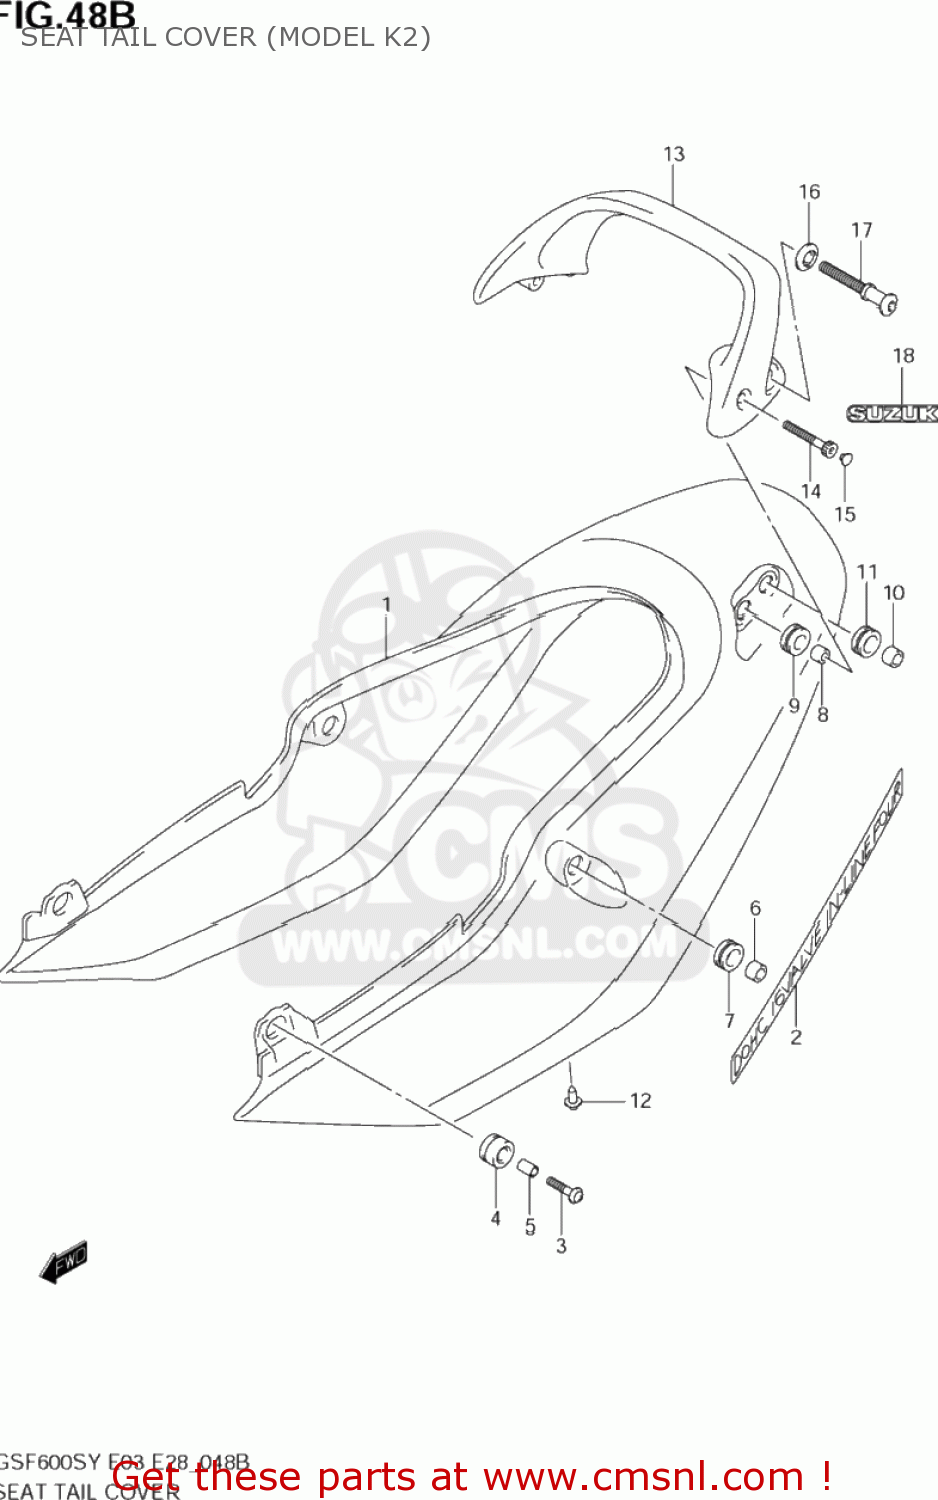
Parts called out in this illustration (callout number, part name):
1	COVER,SEAT TAI
2	EMBLEM,SEAT TAIL COVER(SILVER)
3	SCREW(6X30)
4	CUSHION,SEAT TAIL COVER FR
5	SPACER(6.5X10X13)
6	SPACER,8.5X14X9
7	CUSHION
8	SPACER(6.5X12X9)
9	CUSHION
10	SPACER,8.5X14X9
11	CUSHION
12	CLIP(BLACK)
13	HANDLE,PILLION RIDER(BLUE)
15	CAP(OD:10)
16	WASHER,HOOK
17	HOOK,PILLION RIDER HANDLE
18	EMBLEM,SUZUKI
